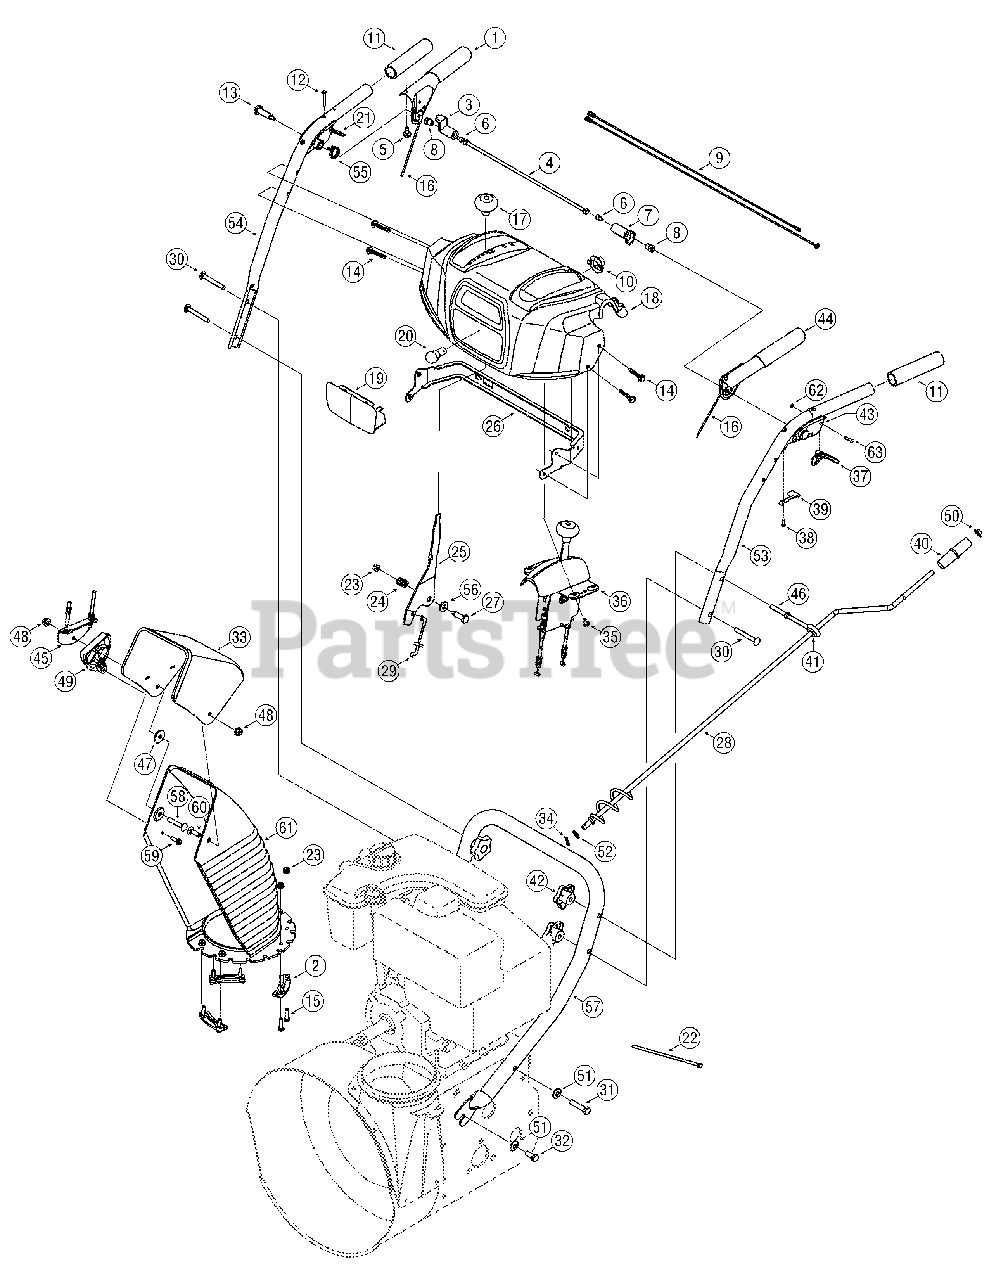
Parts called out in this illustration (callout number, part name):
1	Handle Engage Assy - RH
2	Chute, Flange Keeper
3	Lock Plate
4	Pivot Rod
5	Rubber Bumper
6	Screw, 1/4-20 x.375
7	Clutch Lock Cam
8	Shoulder Nut, 1/4-20
9	Wire Harness
10	Light Socket
11	Handle Grip
12	Screw, #10-24 x 0.375
13	Shoulder Screw, 1/4-20 x 1.345
14	Screw, 1/4-20 x 1.625
15	Screw, 1/4-20 x 1.00
16	Cable Assy, Auger/Drive
17	Shift Knob
18	Handle Panel
20	Lamp
21	Handle Clutch Lock - RH
22	Cable Tie
23	Flange Lock Nut, 1/4-20
24	Compression Spring
27	Shoulder Screw
29	Speed Selector Cable
30	Screw, Carriage, 5/16-18 x 2.5
31	Screw, Hex, 3/8-16 x 1.75
32	Screw, Hex, 3/8-16 x .88
33	Upper Chute
34	Pin, Internal Cotter Pin
35	Hi-Lo Screw, 1/4-15 x 0.5
36	2-Way Chute Control Assy
37	Steering Control
38	Screw, #8-16 x 0.50
39	Clutch Lock Spring
40	Knob, Crank
41	Grommet, Rubber
42	Knob, Star, 5/16-18
43	Handle Clutch Lock - LH
44	Handle Engage Assy - LH
47	Flat Washer
48	Flange Lock Nut, 5/16-18
49	Chute Tilt Cable Guide
50	Cap, Push, 3/8
51	Washer, Bel, .375 x .87 x .063
52	Washer, .375 x .738 x .063
55	Torsion Spring
56	Flat Washer
58	Bolt, Carriage, 5/16-18 x 1.75
59	Hi-Lo Screw, 1/4-15 x .75
60	Screw, Carriage, 5/16-18 x 1.0
61	Lower Chute
62	Ring, Retainer
